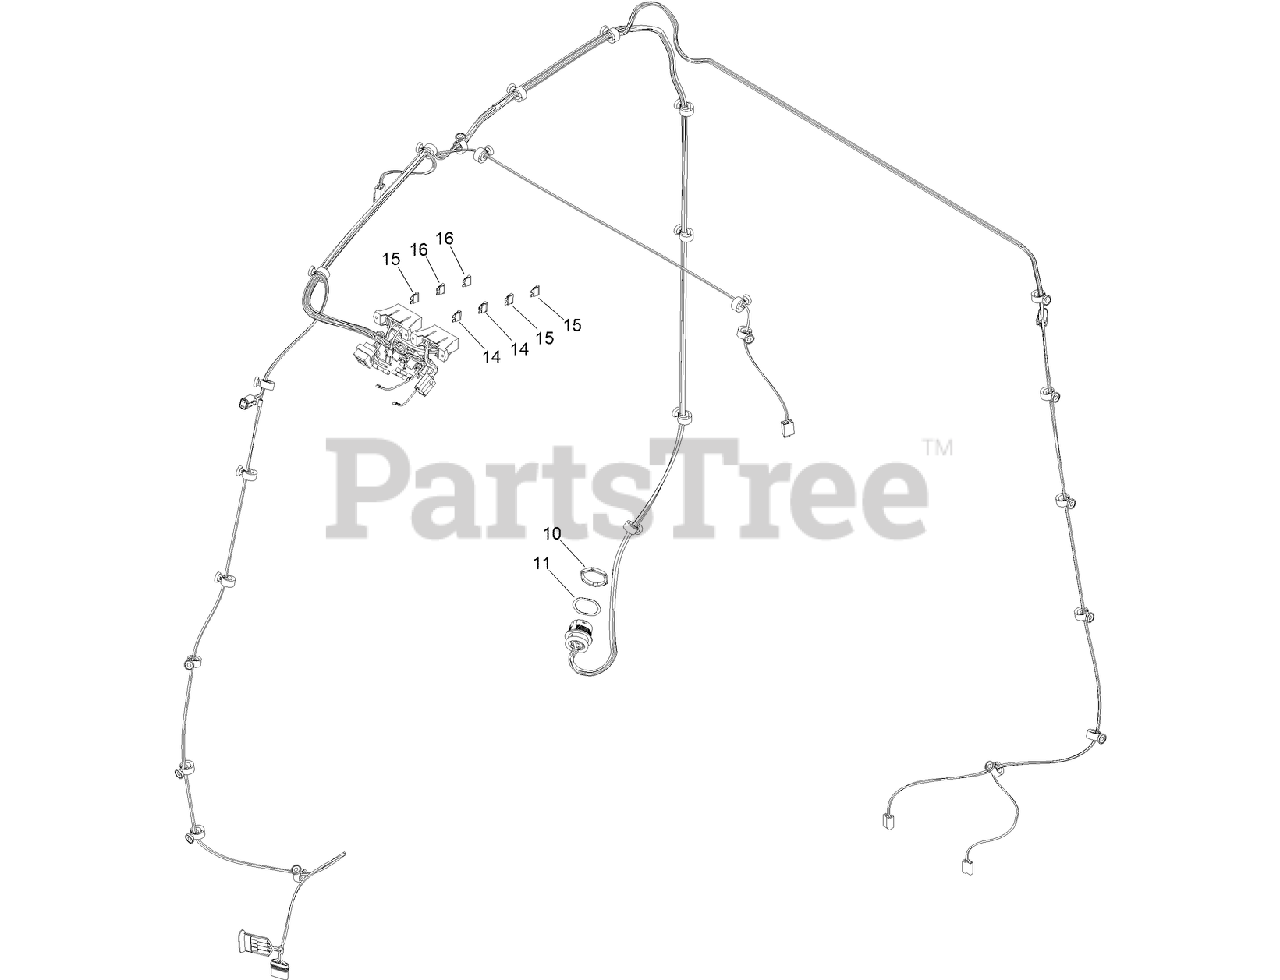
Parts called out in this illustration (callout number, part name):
10	NUT-CONNECTOR
11	WASHER-LOCK
14	FUSE-BLADE, 10 AMP
15	FUSE-BLADE, 15 AMP
16	FUSE-BLADE, 30 AMP
